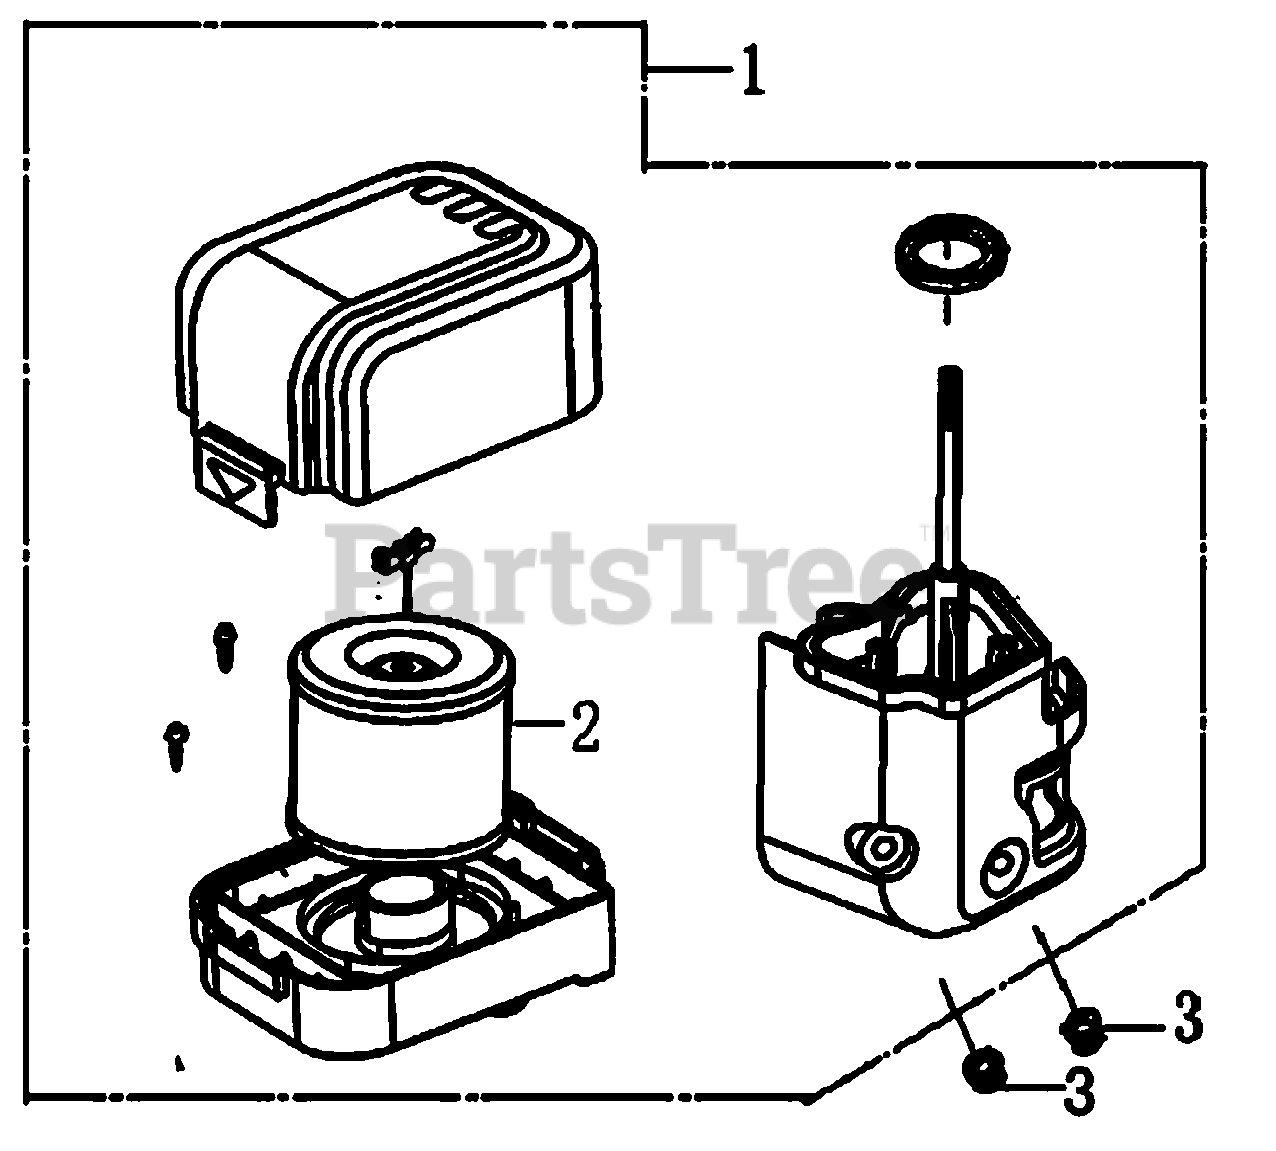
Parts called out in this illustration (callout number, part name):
1	AIR CLEANER ASSY
2	ELEMENT ASSY. , AIR CLEANER
3	NUT , FLANGE , 6MM
